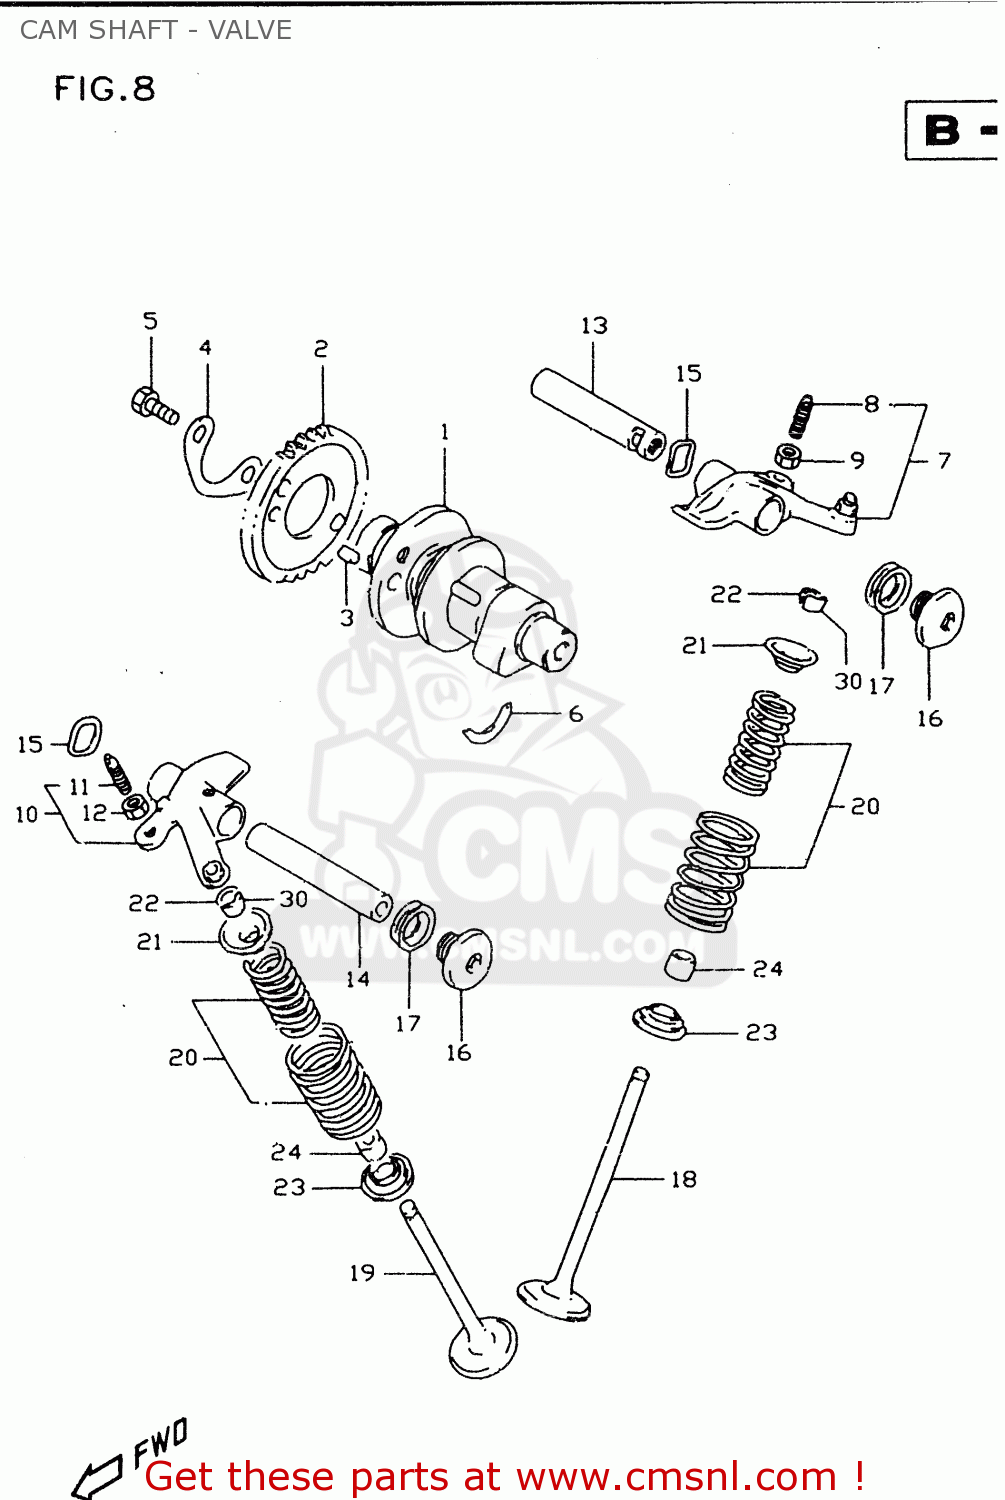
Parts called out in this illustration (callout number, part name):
1	CAMSHAFT COMP
2	SPROCKET,CAMSHAFT
3	PIN(5X8)
4	WASHER,SPROCKET
5	BOLT(6X10.5)
6	C RING
7	ARM,VALVE ROCKER,INTAKE
8	SCREW,TAPPET ADJUSTING
9	NUT,TAPPET ADJUSTING
10	ARM,VALVE ROCKER EXHAUST
11	SCREW,TAPPET ADJUSTING
12	NUT,TAPPET ADJUSTING
13	SHAFT,VALVE ROCKER ARM INTAKE
14	SHAFT,VALVE ROCKER ARM EXHAUST
15	WASHER
16	PLUG,14X12
17	GASKET(13.8X18.8X4.8) (NAS)
18	VALVE,INTAKE
19	VALVE,EXHAUST
20	SPRING SET,VALVE
21	RETAINER,VALVE SPRING
22	COTTER VALVE
23	SEAT,VALVE SPRING
24	SEAL,OIL(5X10X9.7)
